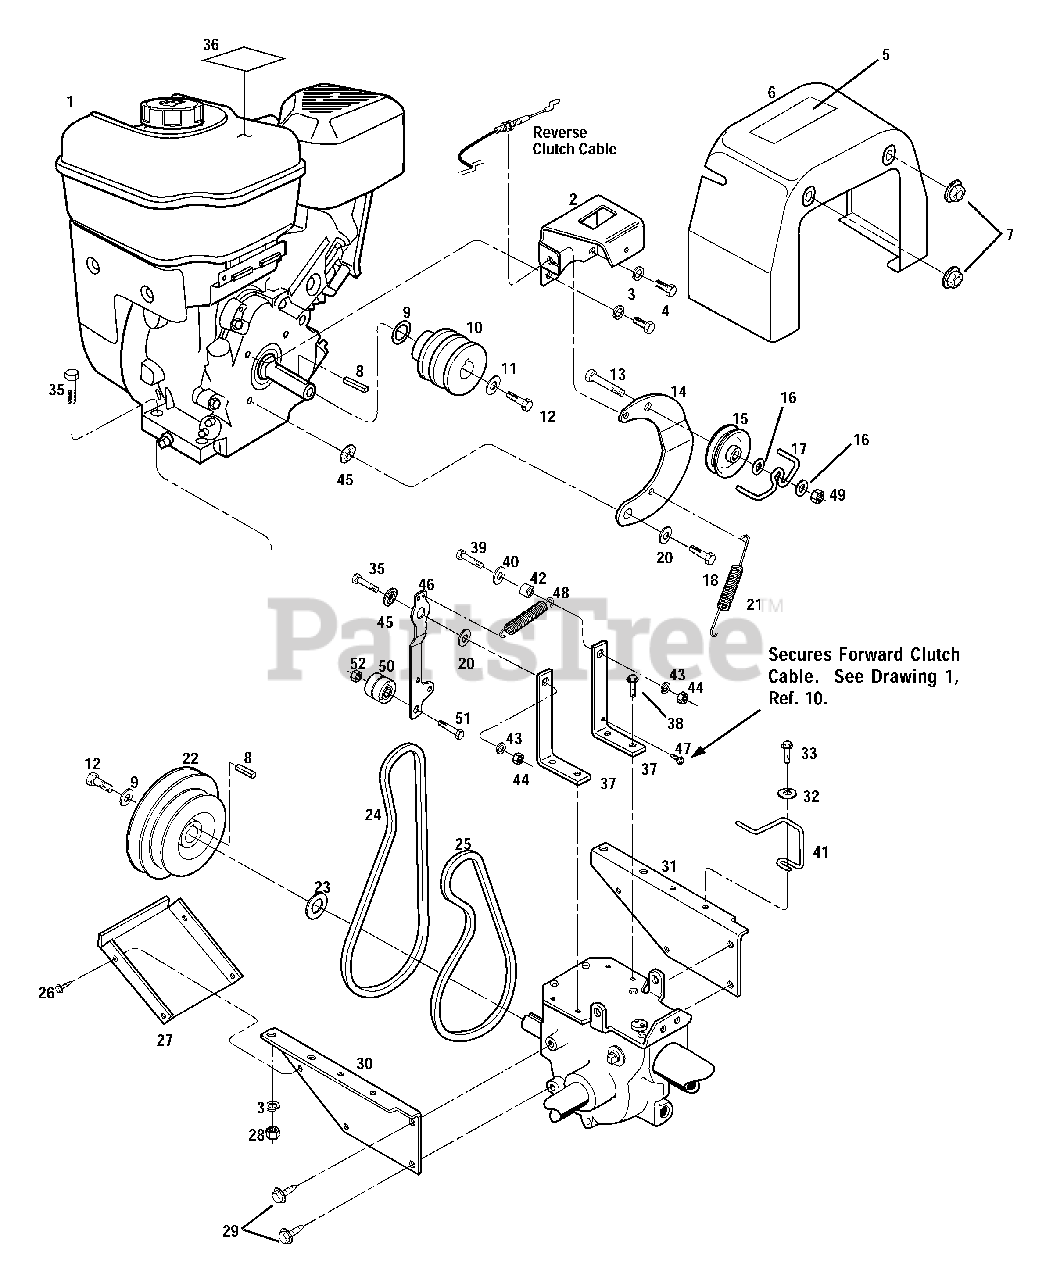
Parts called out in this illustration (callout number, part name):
1	Engine - standard recoil start
2	Bracket, Clutch Cable
3	Lockwasher-5/16
4	Hex Hd. Screw, 5/16-24 x 1/2
5	Decal, Hot Surfaces/Belt Warning
6	Cover
7	Flange Lock Nut, 5/16-18
8	Key, 3/16 x 1-1/2
9	Shim
10	Pulley, Engine Drive
11	Belleville Washer
12	Hex Hd. Screw, 5/16-24 x 1-1/8
13	Hex Hd. Screw, 5/16-18 x 2
14	Reverse Idler Arm
15	Pulley, Reverse Idler
16	Flat Washer, 5/16
17	Belt Guide, Wire Formed
18	Hex Head Screw, 5/16-24 x 1
20	Washer, Flat, 1-1/8
21	Spring, Reverse Return
22	Transmission Pulley
23	Support Washer
24	Reverse Clutch Belt
25	Forward Clutch Belt
26	Hex Hd. Screw, #10-32 x 1/2, self-tapping
27	Guard, Belts/Pulleys
28	Hex Nut, 5/16-18
29	Hex Flange Screw, 5/16-18 x 3/4
30	Engine Support Bracket, left side
31	Engine Support Bracket, right side
32	Flat Washer, 1/4
33	Hex Flange Screw, 1/4-20 x 3/4
35	Hex Hd. Screw, 5/16-18 x 1-1/2
36	Decal, Stabilization
37	Mounting Bar
38	Hex Flange Screw, 5/16-18 x 1
39	Hex Hd. Screw, 5/16-18 x 2-1/4
40	Flat Washer, 5/16'
41	Belt Guide, Wire Formed, Fwd Belt
42	Pivot Bushing
43	Lockwasher, 5/16
44	Hex Nut, 5/16-18
45	Washer, Shoulder
46	Idler Arm, Forward Tiller Direction
47	Screw, self tapping, #10-24
48	Spring
49	Hex Locknut, 5/16-18
50	Idler Pulley, Forward
51	Screw, 3/8-18 x 1-3/4
52	Hex Locknut, 3/8-16
